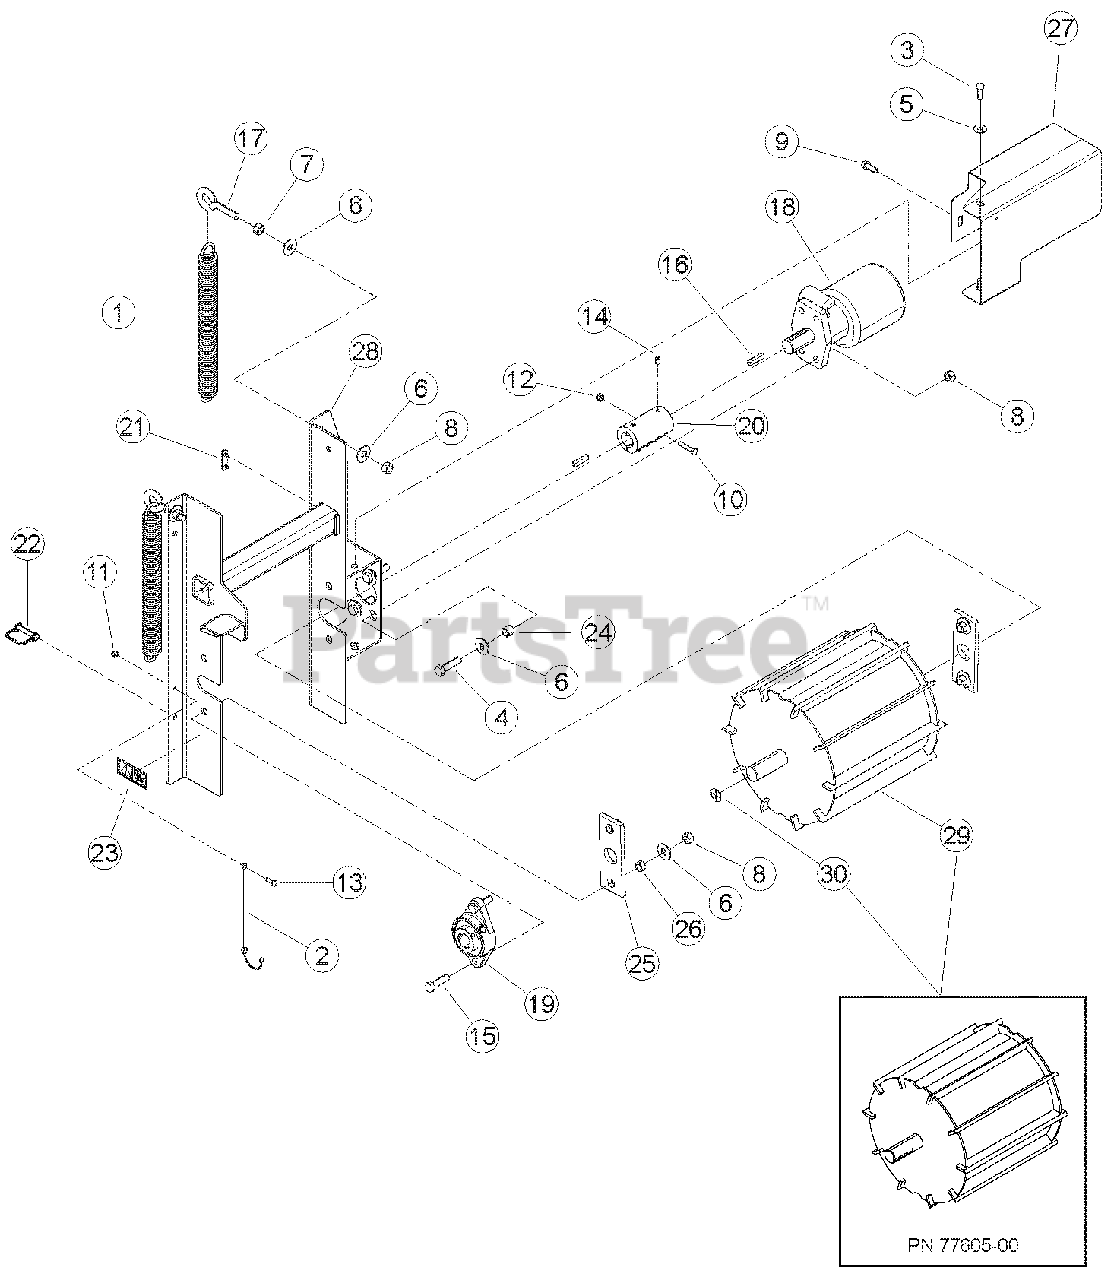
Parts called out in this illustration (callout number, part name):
1	SPRING, EXTENSION
2	LANYARD, NYLON
3	BOLT, 3/8 NC X 1 HEX HD GR5 ZP
4	BOLT, 1/2 X 2 HEX HD
5	WASHER, 3/8 FLAT ZP
6	WASHER, 1/2 FLAT ZP
7	NUT, 1/2 HEX NC ZP
8	NUT, 1/2 CENTERLOCK GRB ZP
9	BOLT, 3/8 X 1 THREAD CUT
10	BOLT, 5/16 X 1-1/2 HEX HD
11	NUT, 1/4 NYLOCK
12	NUT, 5/16 NYLOCK
13	BOLT, 1/4 X 3/4 HHCS GR5 NF ZP
14	SETSCREW, 3/8-16 X 1/2 SET
15	BOLT, 1/2 X 1-3/4 HEX HD
16	KEY, 5/16 X 1-3/4 SQUARE
17	I-BOLT, 1/2 X 2
18	MOTOR, 45 CU. IN. HYDRAULIC
19	BEARING, 1-1/4 2 BOLT FLANGE
20	COUPLER, 1-1/4 SHAFT
21	WEAR PAD, STD. SPRING HD FRONT
22	PIN, 3/8 X 1-1/2 SNAP
23	DECAL, CRUSHING ISO
24	SPACER, .75 X .62
25	BEARING, ROLLER SLIDE
26	SPACER, .75 OD X .37
27	WELDMENT, MOTOR COVER
28	WELDMENT, ROLLERSLIDE
29	WELDMENT, FEED ROLLER
30	DECAL, ROTATING SHAFT
